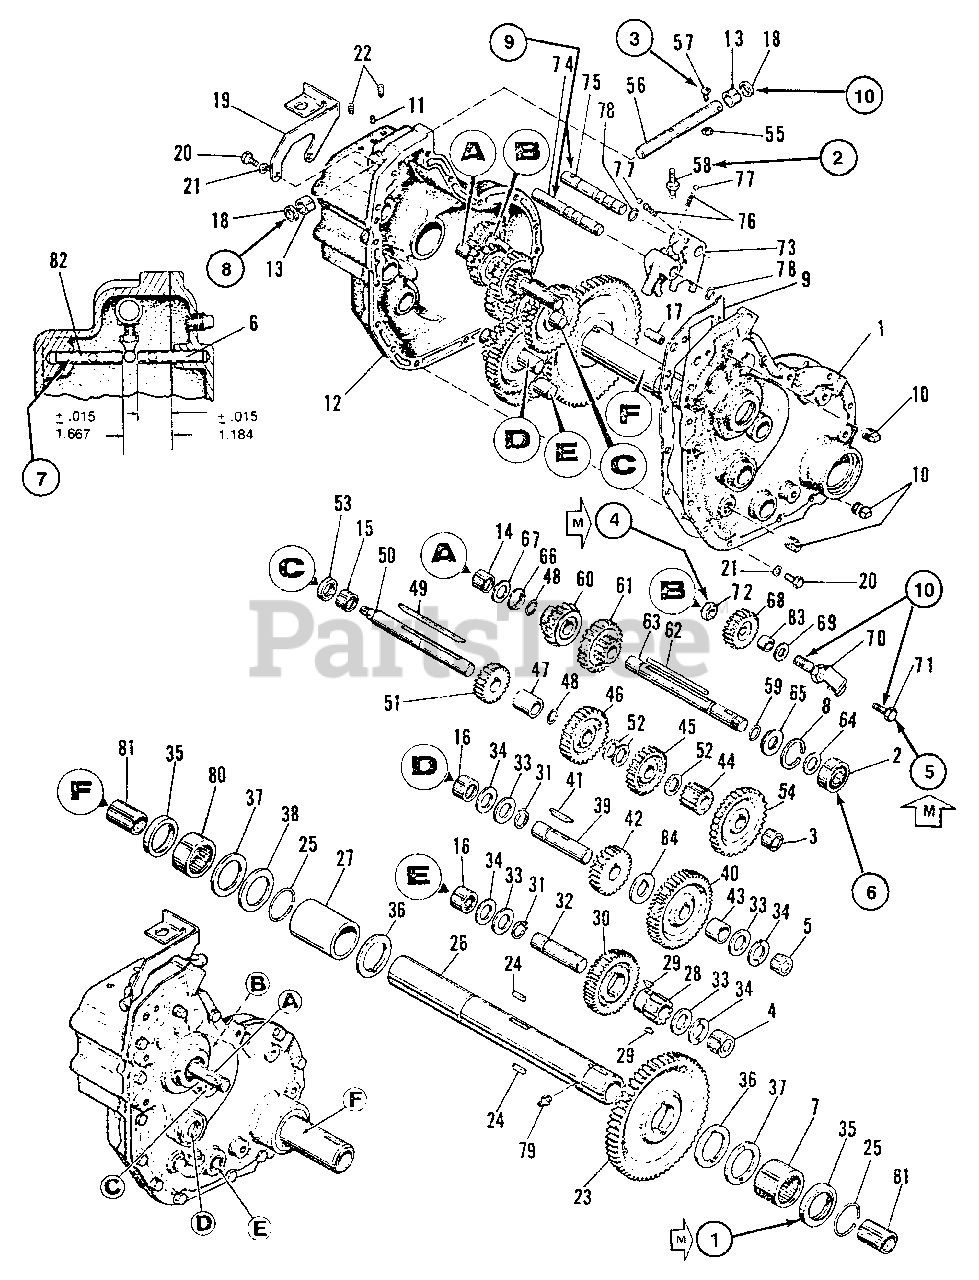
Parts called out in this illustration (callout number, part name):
1	COVER, Gear Case
2	BEARING, Ball
3	BEARING, Needle
4	BEARING, Needle
5	BEARING, Needle
6	ROLL PIN ASSEMBLY
7	BEARING, Needle
8	RING, Retaining
9	GASKET, Gear Case
10	PLUG, Pipe, Sq. Hd., 3/8
12	GEAR CASE ASSEMBLY
13	SPACER, Diff.
14	BEARING, Needle
15	BEARING, Needle
16	BEARING, Needle
17	PIN, Spring, 3/8x1
19	SUPPORT, Switch
20	CAPSCREW, Hex Hd., 5/16-13 x 1
21	LOCKWASHER, 5/16
22	SETSCREW, Soc. Hd., 5/16-18 x 1/2
23	GEAR, Drive
26	TUBE & BUSHING ASSEMBLY
27	SPACER, Axle Tube
28	PINION, 3rd Interm.
29	KEY, Woodruff, No. 6
30	GEAR, 3rd Interm.
31	RING, Retaining
32	SHAFT, 3rd Interm.
36	WASHER, Axle Tube
37	WASHER, Axle Tube
38	WASHER, Axle Tube
39	SHAFT, 2nd Interm.
40	GEAR, 2nd Interm.
42	PINION, 2nd Interm.
44	PINION, 1st Interm.
45	PINION, Driver II
46	GEAR, Driver II
48	RING, Retaining
50	SHAFT, 1st Interm.
51	PINION, Rev. & IV
54	GEAR, Driven I
55	NUT, Jam Hex, 5/16-18
56	ROD, Shift
57	BOLT CARRIAGE, Special
58	STEM, Shift
59	RING, Retaining
60	PINION ASSEMBLY REV. & II
61	PINION ASSEMBLY I & II
63	SHAFT, Pulley
70	REV. GEAR PIN ASSEMBLY
71	CAPSCREW, Flange, Whiz, 3/8-16 x 1-1/4
72	LOCKNUT, Hex, 1/2-20
73	FORK, Shift
74	SHAFT, Shifter
75	SHAFT, Shifter, Hi-Lo
77	BALL, Shiftlock
78	RING, Retaining
79	FITTING, Grease
80	BEARING, Needle
82	ROLL PIN ASSY
83	SPACER, Rev. Gear
85	CAPSCREW, Hex Hd., 5/16-18 x 1-1/2
